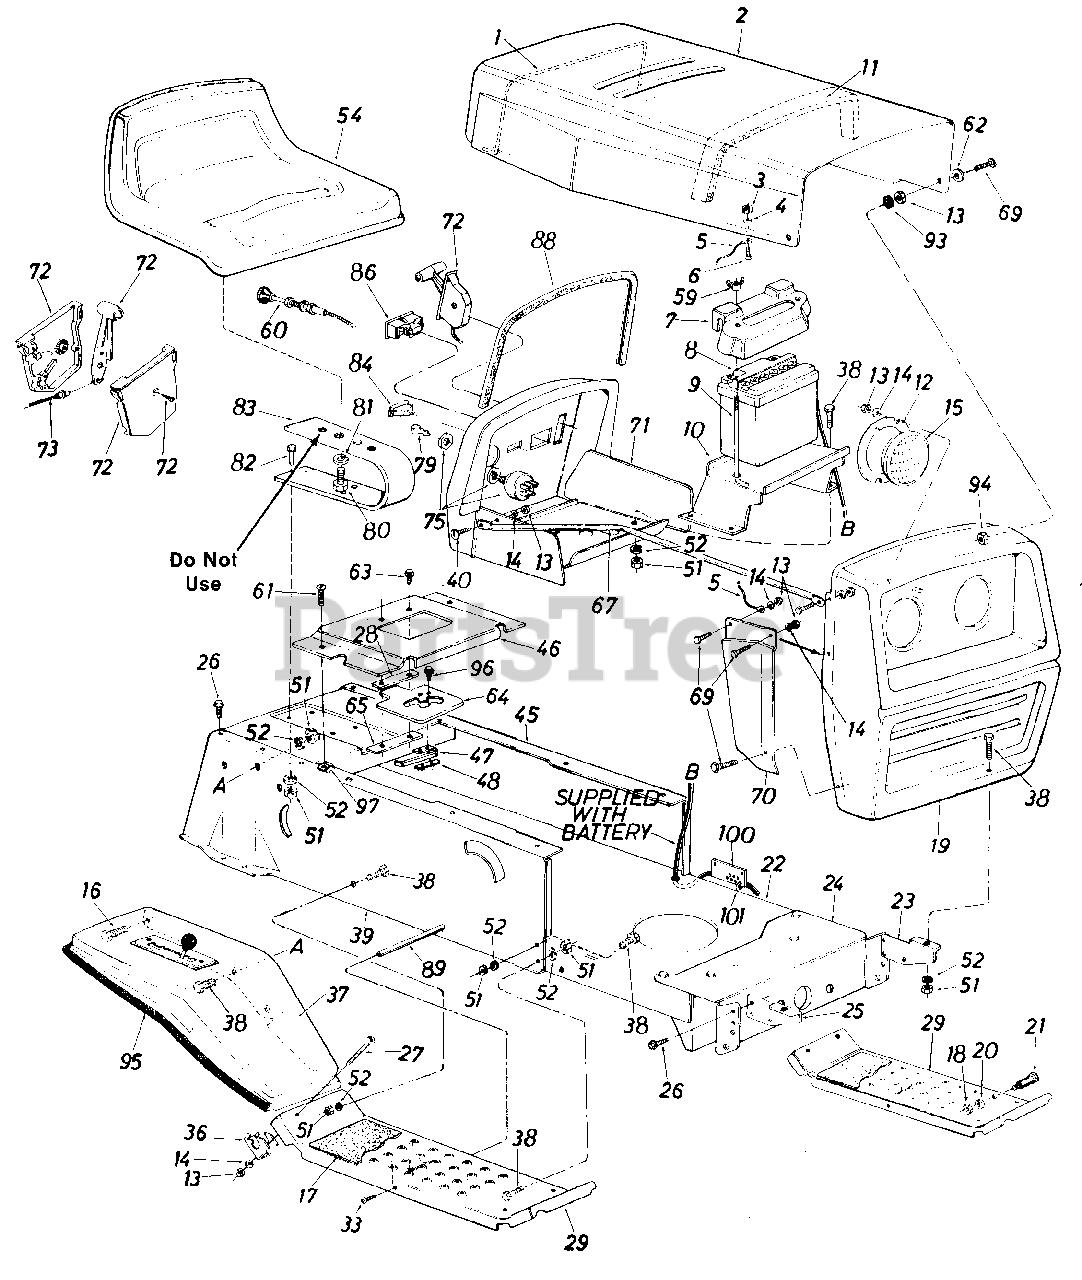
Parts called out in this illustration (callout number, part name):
1	Hood Spring
2	Hood
3	Hex Sems Nut #10-24 Thd.
4	Fl-Wash. .281" I.D. x .62" O.D. x .051
5	Hood Stop 7" Lg.
6	Truss Hd. Scr. #10-24 x 1/2"
7	Battery Cover
8	12 Volt Battery
9	Battery Hold Down Rod
10	Battery Bracket
11	PVC Foam-Strip
12	Headlight Retainer
13	Hex Nut 1/4-20 Thd.*
14	L-Wash. 1/4" I.D.
15	Headlight
16	Hex Wash. Hd. Tap Scr. 1/4 x 3/8" Lg.
17	Foot Pad
18	Hex Nut 3/8-16 Thd.
21	Shld. Bolt .50" Dia. x .84
22	Lower Frame
23	Grille Mount Brkt.-L.H.
24	Front Pivot Brkt.
25	Grille Mount Brkt.-R.H.
26	Hex Wash. Hd. AB-Tap Scr. 5/16 x .75" Lg.
27	Truss Hd. Scr. 1/4-20 x 1.75" Lg.*
28	Spacer Plate
29	Running Board
33	Truss Mach. Scr. 5/16-18 x .75" Lg.
36	Fender Clamp
37	Fender
39	R.H. Side Frame
40	Hex Bolt 1/4-20 x .62" Lg.
45	L.H. Side Frame
46	Shift Cover
47	Reverse Safety Switch
48	Insulator Nut Plate
51	Hex Nut 5/16-18 Thd.*
52	L-Wash. 5/16" I.D.
54	Seat Ass'y.
59	Wing Nut 1/4-20 Thd.-Plastic
60	Choke Control
61	Truss Mach. Tap Scr. #10 x .50" Lg.
62	Fl-Wash. .296 I.D. x .62 O.D.
63	Truss Mach. Scr. 1/4-20 x .75" Lg.
64	Gear Selection Plate
65	Clamping Plate
69	Truss Hd. Scr. 1/4-20 x .75" Lg.
70	R.H.-Grille Side Panel
71	Dash Panel Ass'y.
72	Throttle Control Box Ass'y.
73	Throttle Control Wire
75	Ignition Switch
79	Ignition Key
80	Hex Bolt 1/2-13 x 1.00" Lg.
81	L-Wash. 1/2" I.D.
82	Hex Bolt 5/16-18 x 1.00" Lg.*
83	Seat Spring 5.5" High
84	Light Switch
86	Ammeter
88	Molding Strip 27" Lg.
89	Running Board Rod
93	Rubber Wash. 1/2" I.D. x 1.0 O.D. x .25"
94	Hex Sems Ins. L-Nut 1/4-20 Thd.
95	Trim Strip
96	Hex Wash. Hd. AB-Tap Scr. #8 x .50" Lg.
97	Speed Nut #10Z
100	Brake Cable Bracket
101	Cable Tie
